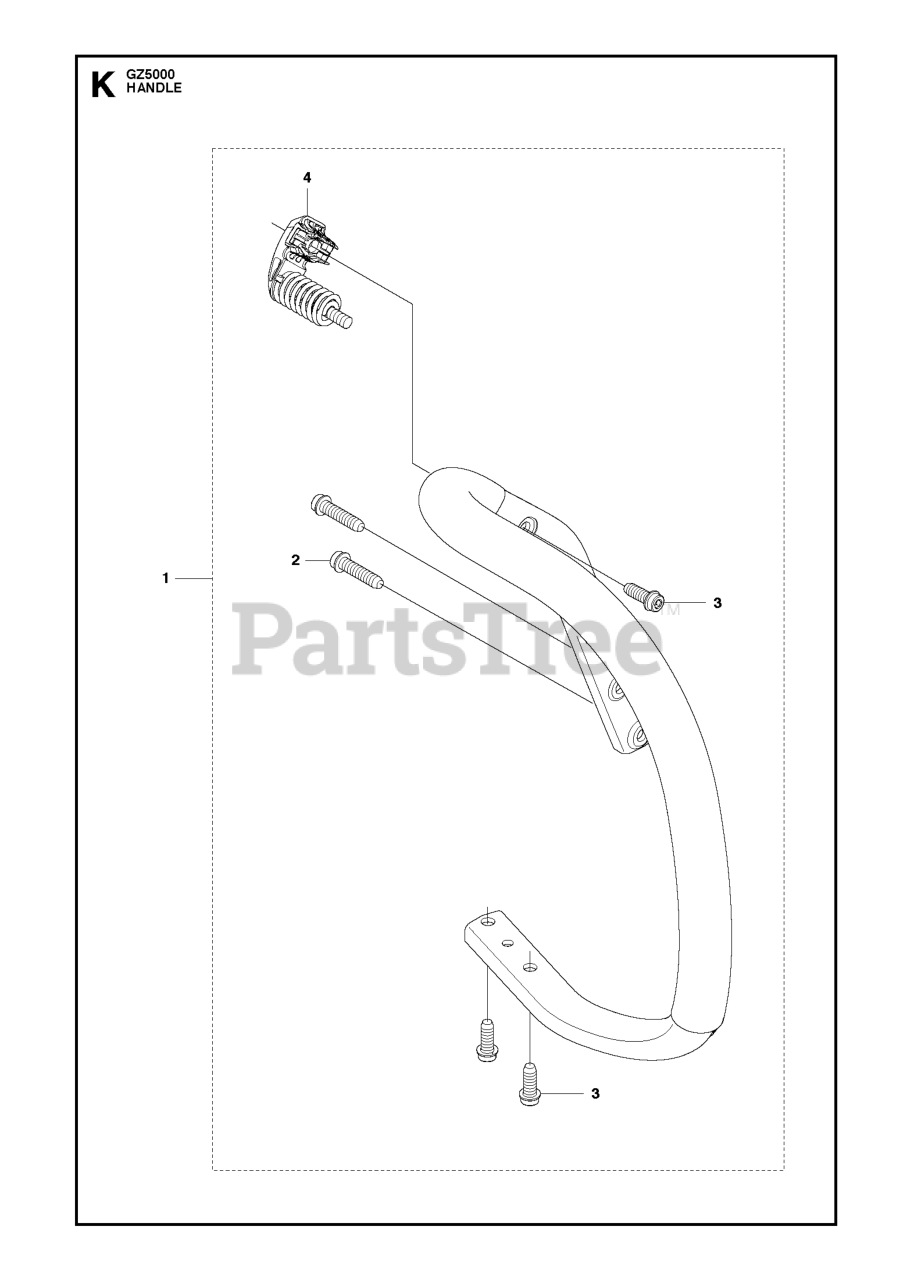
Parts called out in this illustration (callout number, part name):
1	FRONT HANDLE ASSY
3	SCREW ITXSCFT PL6X16 T27 10.9
4	ANTIVIBRATION ELEMENT ASSY
